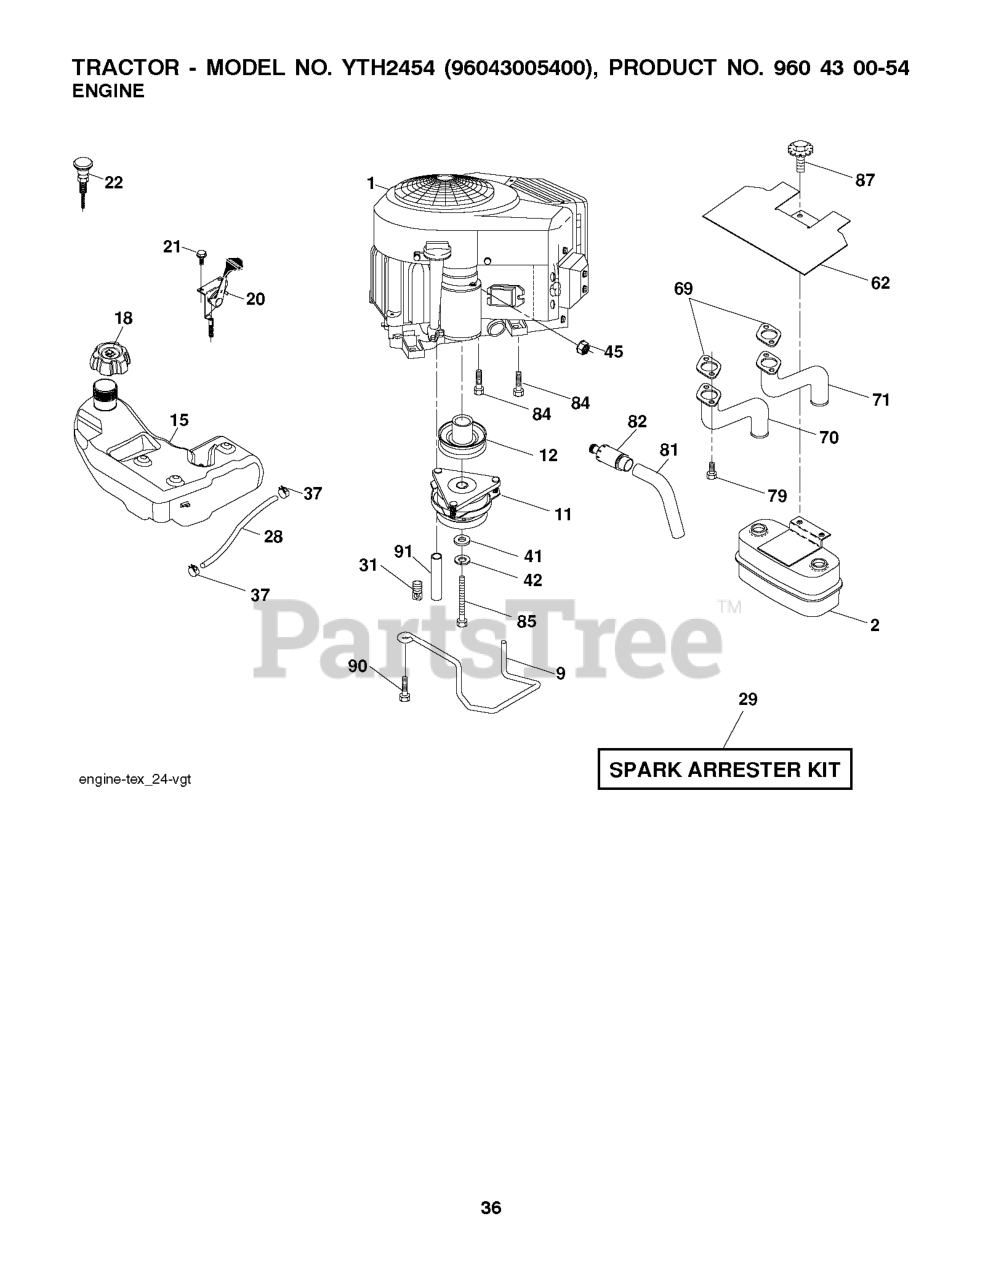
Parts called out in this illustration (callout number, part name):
2	MUFFLER.TWIN.CYL.LOW.TONE
9	KEEPER.BELT.ENGINE.4.2
11	CLUTCH MZ ZTR GT.48/54"1.125"
12	PULLEY ENGINE
15	TANK.FUEL.4GAL
18	CAP.FUEL.TANK.3"GREY
20	THROTTLE CABLE
21	SCREW.#10 X 0.750.BOS
22	CONTROL.CHOKE.ERGO.PUSH-IN.BLA
28	LINE.FUEL.64"REAR.EMIS
29	KIT.SPARK ARRESTOR 794945 B&S
37	HOSE CLAMP
42	LOCKWASHER
45	NUT
62	RP SHIELD HEAT MUFFLER
69	GASKET.MUFFLER
70	RP.EXHAUST.TUBE.LH.BS/TWIN
71	EXHAUST.TUBE.RH.BS/TWIN
79	SCREW.SOCKET.HEAD.5/16-18
81	TUBE, DRAIN OIL ASM.
82	PLUG DRAIN OIL EASY
84	SCREW.3/8-16
85	BOLT HEX 7/16-20 X 3.75 GR. 5
87	BOLT.5/16-18UNCX1.W/SEMS.BLK
90	SCREW 3/8-16X1
91	BUSHING.1.375OD
